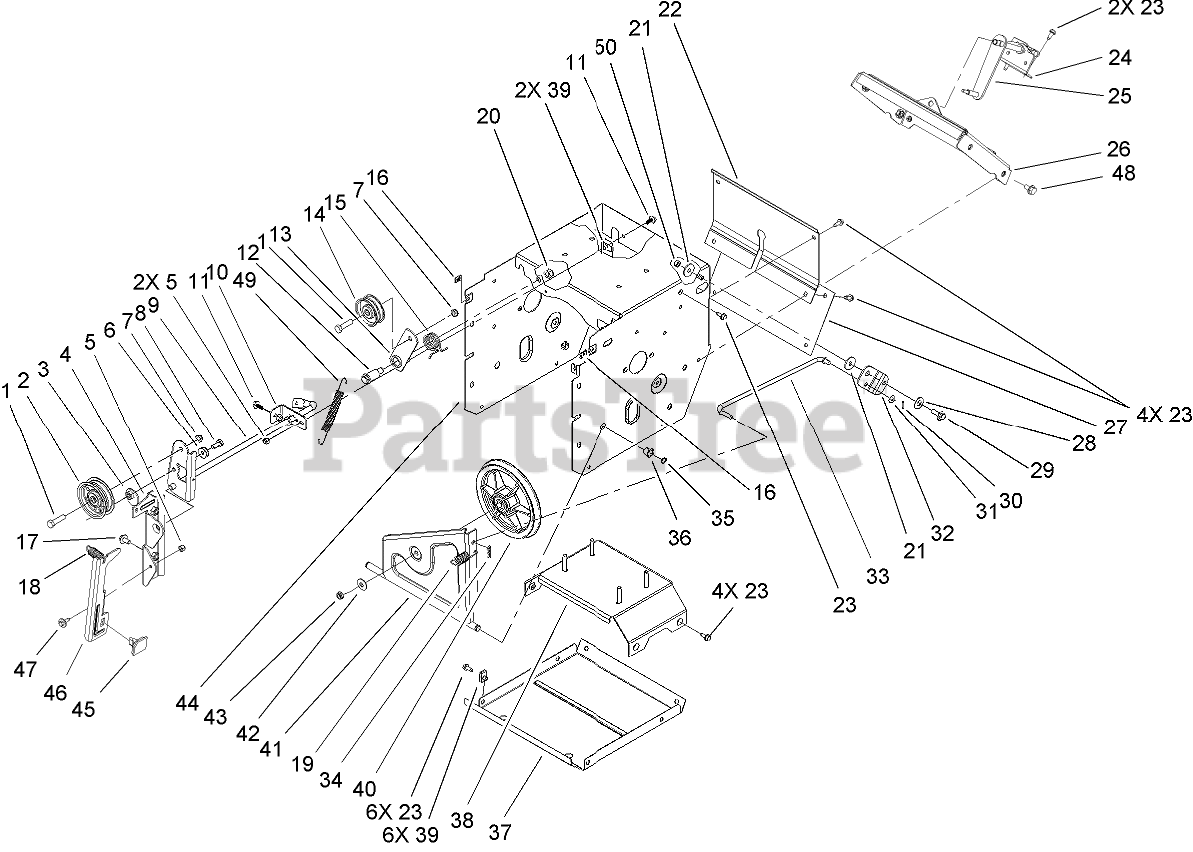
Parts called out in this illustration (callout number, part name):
1	SCREW-HH
2	PULLEY-IDLER
4	BRACKET-IDLER, IMPELLER
5	NUT-LOCK, NI
6	WASHER-BELLEVILLE
7	NUT-LOCK, NI
8	SCREW-HH
9	AUGER CLUTCH ASM
10	BRACKET-REAR, CLUTCH
11	SCREW-HHF
12	BOLT-SHOULDER
13	ARM-IDLER, TRACTION
14	PULLEY-IDLER
15	SPRING-TORSION, RH
16	NUT-SPEED, U-TYPE
17	SCREW-HHF
18	SPRING-EXTENSION
19	SPRING-EXTENSION
20	NUT-LOCK, NI
21	WASHER-PIVOT
22	COVER-UPPER
23	SCREW-HWH
24	BRACKET-SHIFT ROD
25	LEVER-CONTROL, TRACTION
26	SHIFT PLATE ASM
27	COVER-LOWER
28	WASHER
29	SCREW-SHOULDER
30	PIN-COTTER
31	WASHER-PLAIN
32	BELLCRANK-DRIVE
33	LINK-CONTROL, SPEED
34	PIN-COTTER
35	RING-RETAINING
36	BUSHING-NYLINER
37	PAN-BOTTOM
38	BRACE FRAME ASM
40	PULLEY-TRACTION
41	PULLEY PIVOT ASM
42	WASHER-BELLEVILLE
43	NUT-HEX
44	FRAME-TRACTION
45	PAD-BRAKE
46	ARM-BRAKE
47	SCREW-SHOULDER
48	SCREW-HWHTF
49	SPRING-EXTENSION
50	NUT-LOCK, NI
